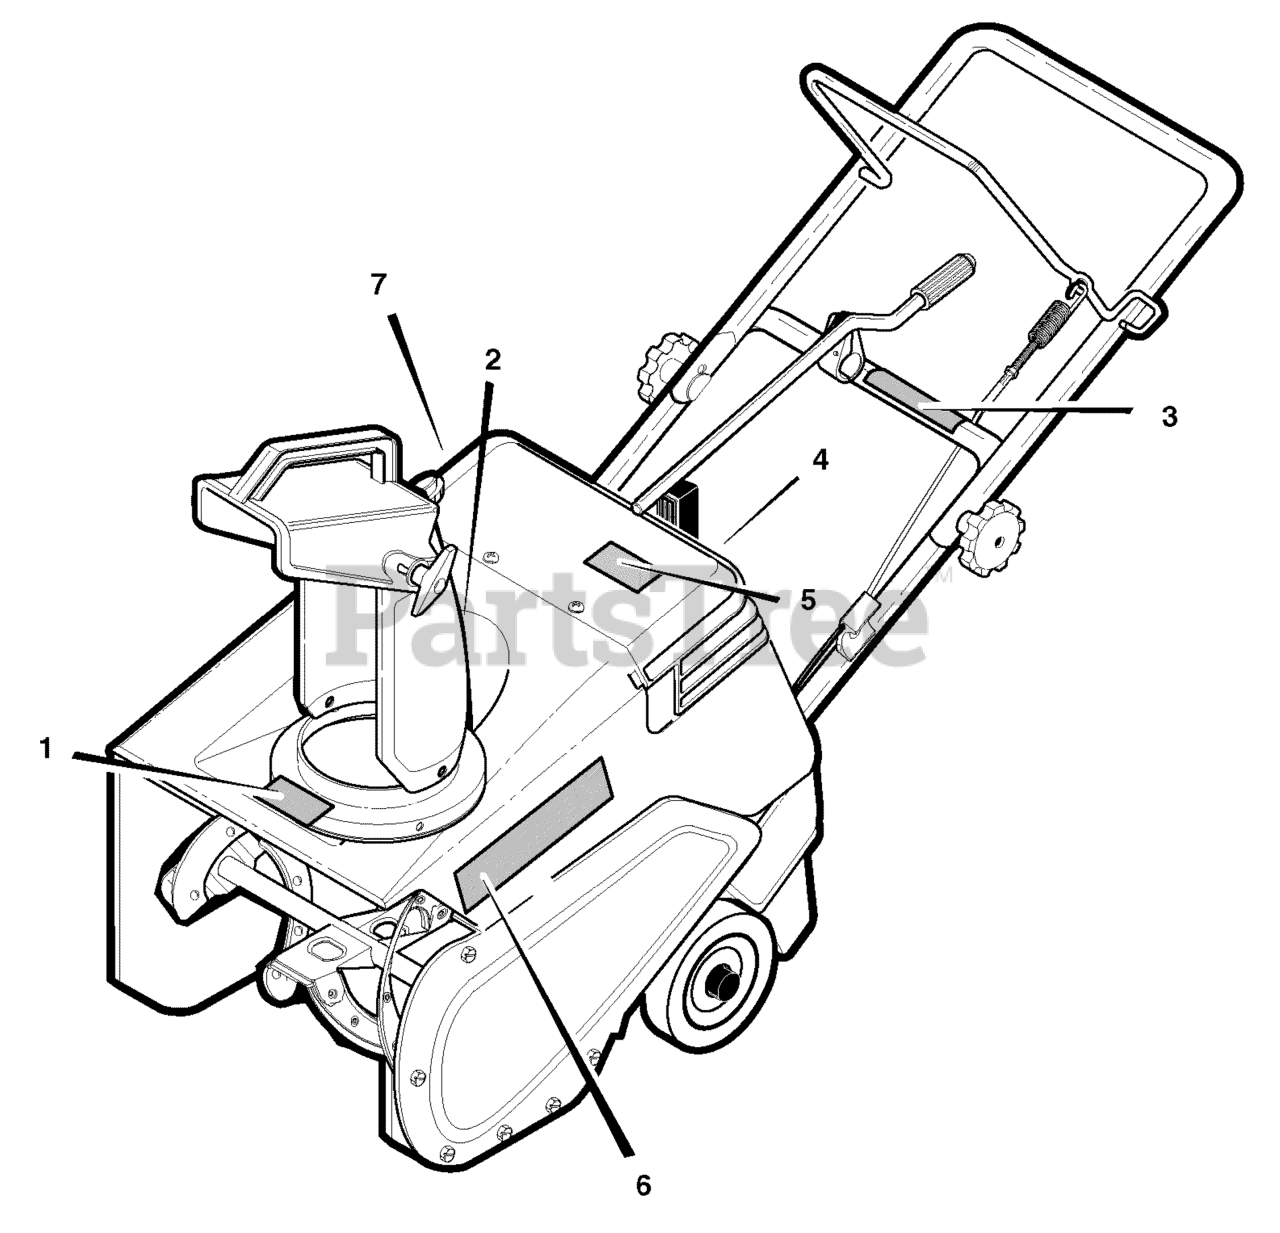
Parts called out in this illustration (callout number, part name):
1	DECAL, DANGER AUGER
2	DECAL, DANGER CHUTE
3	DECAL, AUGER CONTROL
4	DECAL, CONTROL PANEL ST0521E (621500x16NB)
5	DECAL, HOT MUFFLER
6	DECAL, FRONTIER ST0521
7	DECAL, EPA
